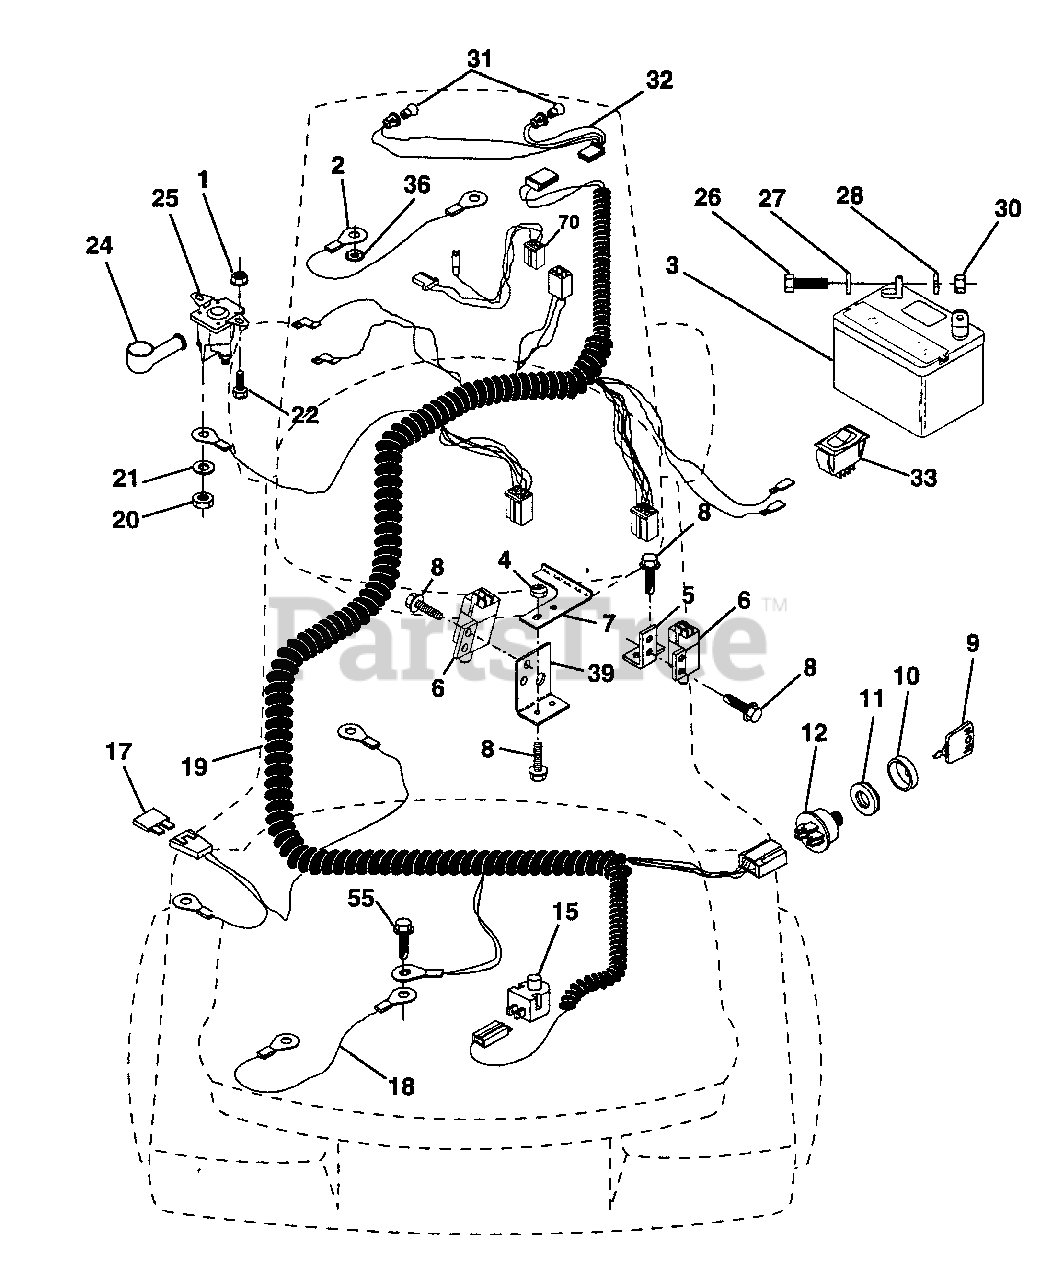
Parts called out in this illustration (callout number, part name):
1	Nut, Hex, Keps 1/4-20
2	Assembly, Cable
3	Battery
4	Nut, Lock #10-24 Unc
5	Bracket, Switch
6	Switch, Interlock, 4 Terminal
7	Keeper, Actuator
8	Screw, Hex Head, Self-Tapping #10-24 x 1/2
9	Key, Molded
10	Cover, Ignition Key
11	Nut, Ignition
12	Switch, Ignition
15	Switch, Plunger
18	Assembly, Cable
19	Harness, Ignition
20	Nut, Hex, Jam 1/4-20
21	Washer, Lock 1/4
22	Bolt, Hex, Fin. 1/4-20 UNC x 1/2 Grade 5
24	Cover, Terminal
25	Solenoid
26	Bolt, Hex Head 1/4-20 UNC x 3/4
27	Washer 9/32 x 5/8 x 16 Gauge
28	Washer, Lock 1/4
30	Nut, Hex, Fin. 1/4-20 UNC
31	Bulb, Light
32	Harness, Headlight
33	Switch, Light
36	Washer, Lock, Internal Tooth 1/4
39	Bracket, Switch Clutch
55	Screw, Thdrol 5/16-28 x 1/2
70	Harness Engine
